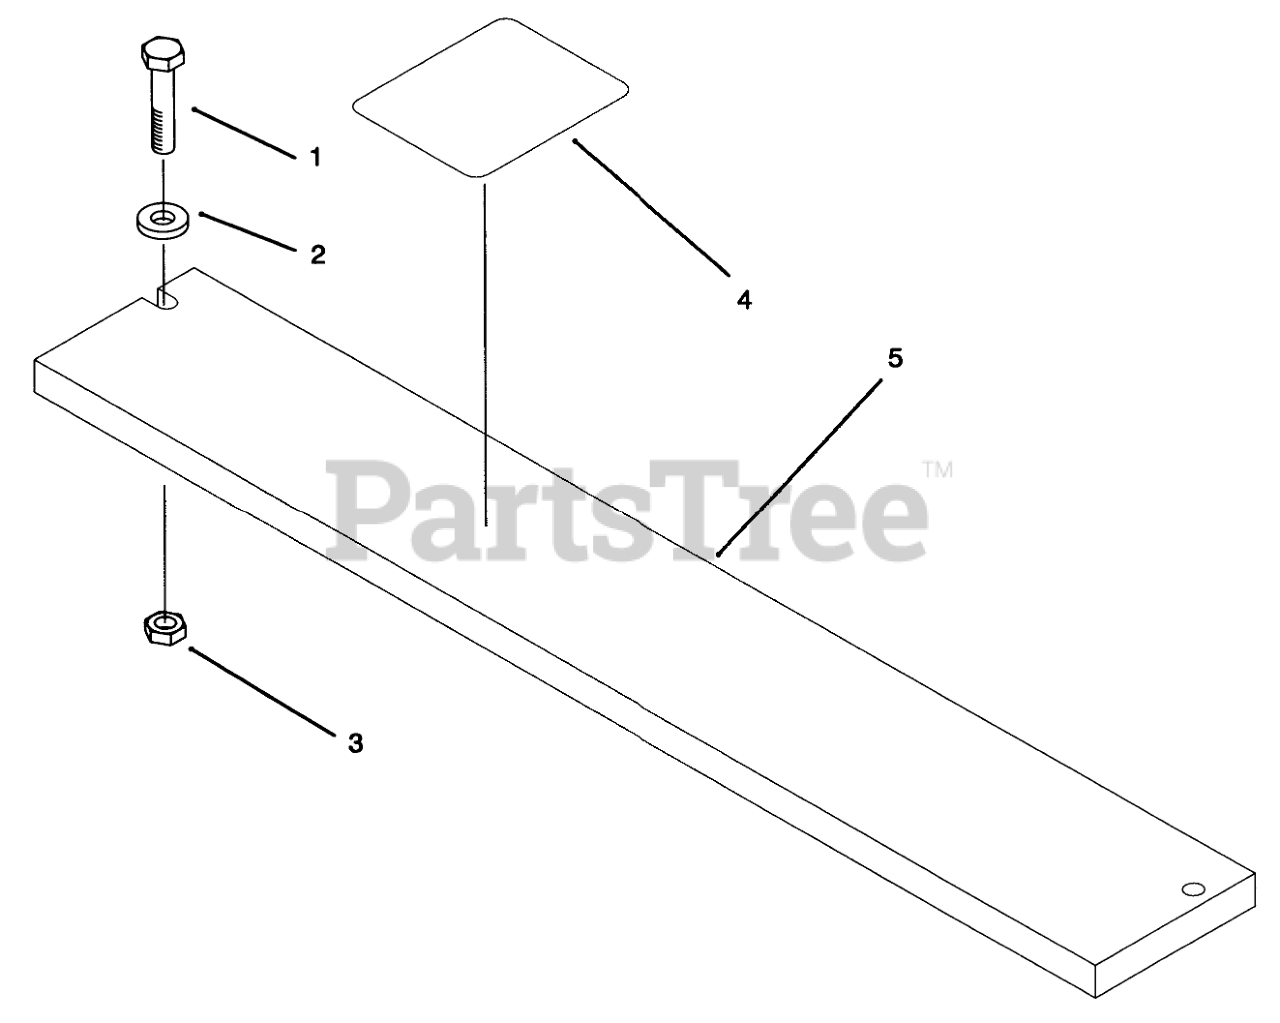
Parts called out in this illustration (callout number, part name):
1	SCREW-HH
2	WASHER-FLAT
3	NUT-LOCK, NI
4	DECAL-WARNING, AUGER
5	Bar-Weight
